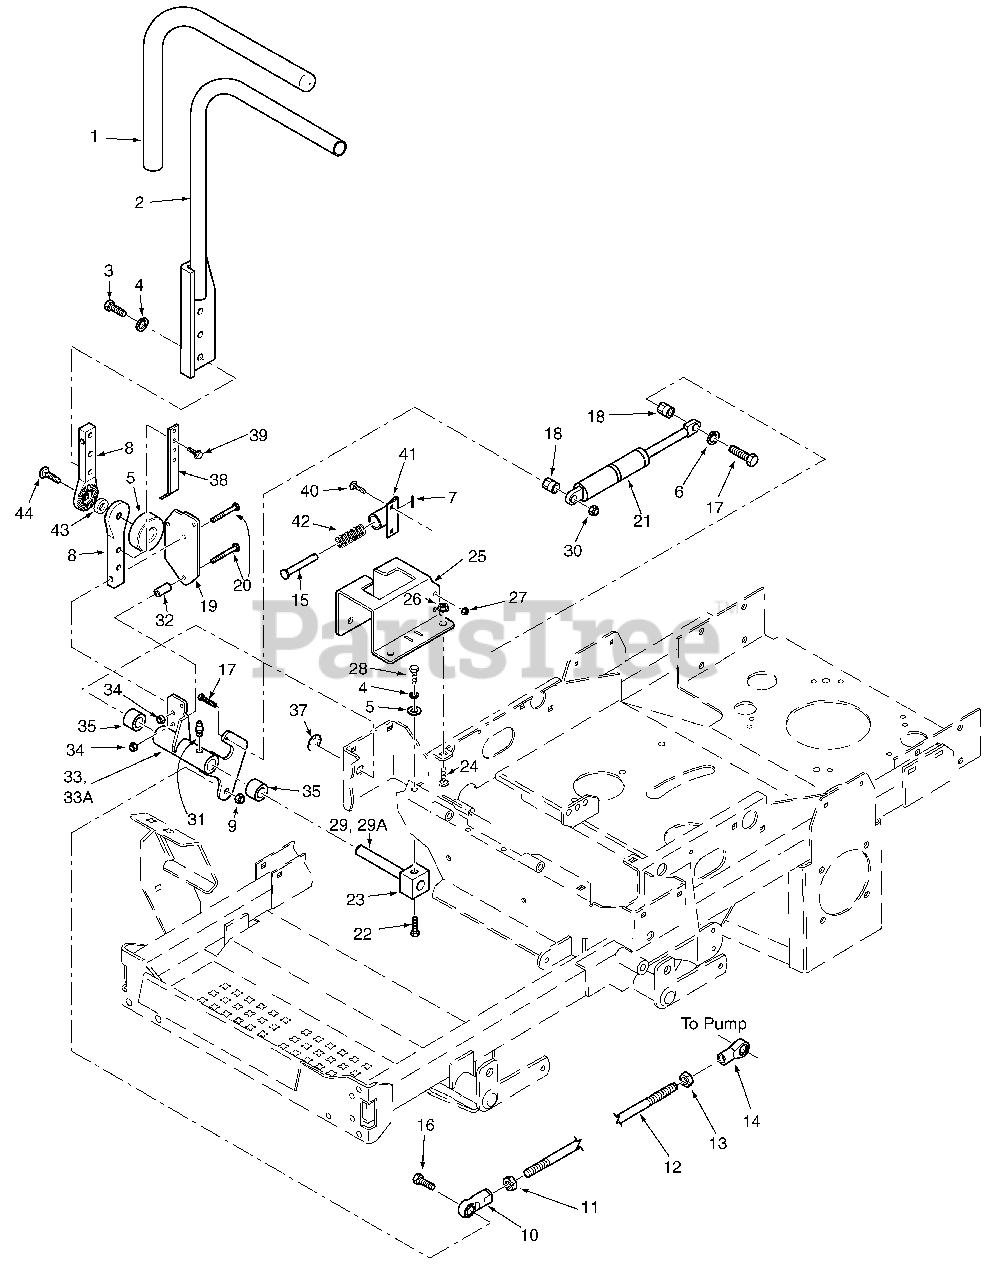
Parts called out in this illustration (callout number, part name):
1	Grip, Control Lever
2	Handle Bar, LH
3	Bolt, Hex Head 3/8-16 x 1-1/4"
4	Lock Washer, 3/8"
6	Flatwasher, 5/16-.375 x .875 x .083
7	Roll Pin, Spring 5/32 x 3/4"
8	Pivot, Control Lever
9	Nut, Elastic Stop 3/8-16
10	Rod End, 3/8-24 RH Female
11	Nut, 3/8-24 RH Thread
12	Rod, Pump Control Linkage
13	Nut, 3/8-24 UNF-2B LH Thread
14	Rod End, 3/8-24 LH Thread
15	Pin Retainer
16	Bolt, Hex Head 3/8-16 x 1-1/2"
17	Bolt, Hex Head 5/16-18 x 1-3/4"
18	Spacer, Pump Dampener
19	Plate, Control Lever
20	Bolt, Hex Head 5/16-18 x 2"
21	Gas Damper
22	Bolt, Hex Head 3/8-16 x 1"
23	Block, Clamping
24	Bolt, Carriage, 5/16-18 x 3/4"
25	Control Plate
26	Nut, Serr., Flange, 5/16-18
27	Nut, Elastic Stop 1/4-20
28	Bolt, Hex Head 3/8-16 x 3/4"
29	Shaft, Steering Control
30	Nut, Elastic Stop 5/16-18
31	Grease Fitting, 1/4-28 Self Tap
32	Spacer, Control
33	Control Lever Assy
34	Nut, Elastic Stop 5/16-18
35	Bushing
36	Flatwasher, 1-1/4 x 49/64 x 16 Ga.
37	Retaining Ring, 3/4" Ext.
38	Bracket, Switch Actuator
39	Bolt, Hex Serr. Flange 5/16-18 x 3/4"
40	Bolt, Carr. 1/4-20 x 3/4"
41	Bracket, Control Return
42	Spring
43	Rubber Spacer
44	Bolt, Carriage 5/16-18 x 1-1/2"
